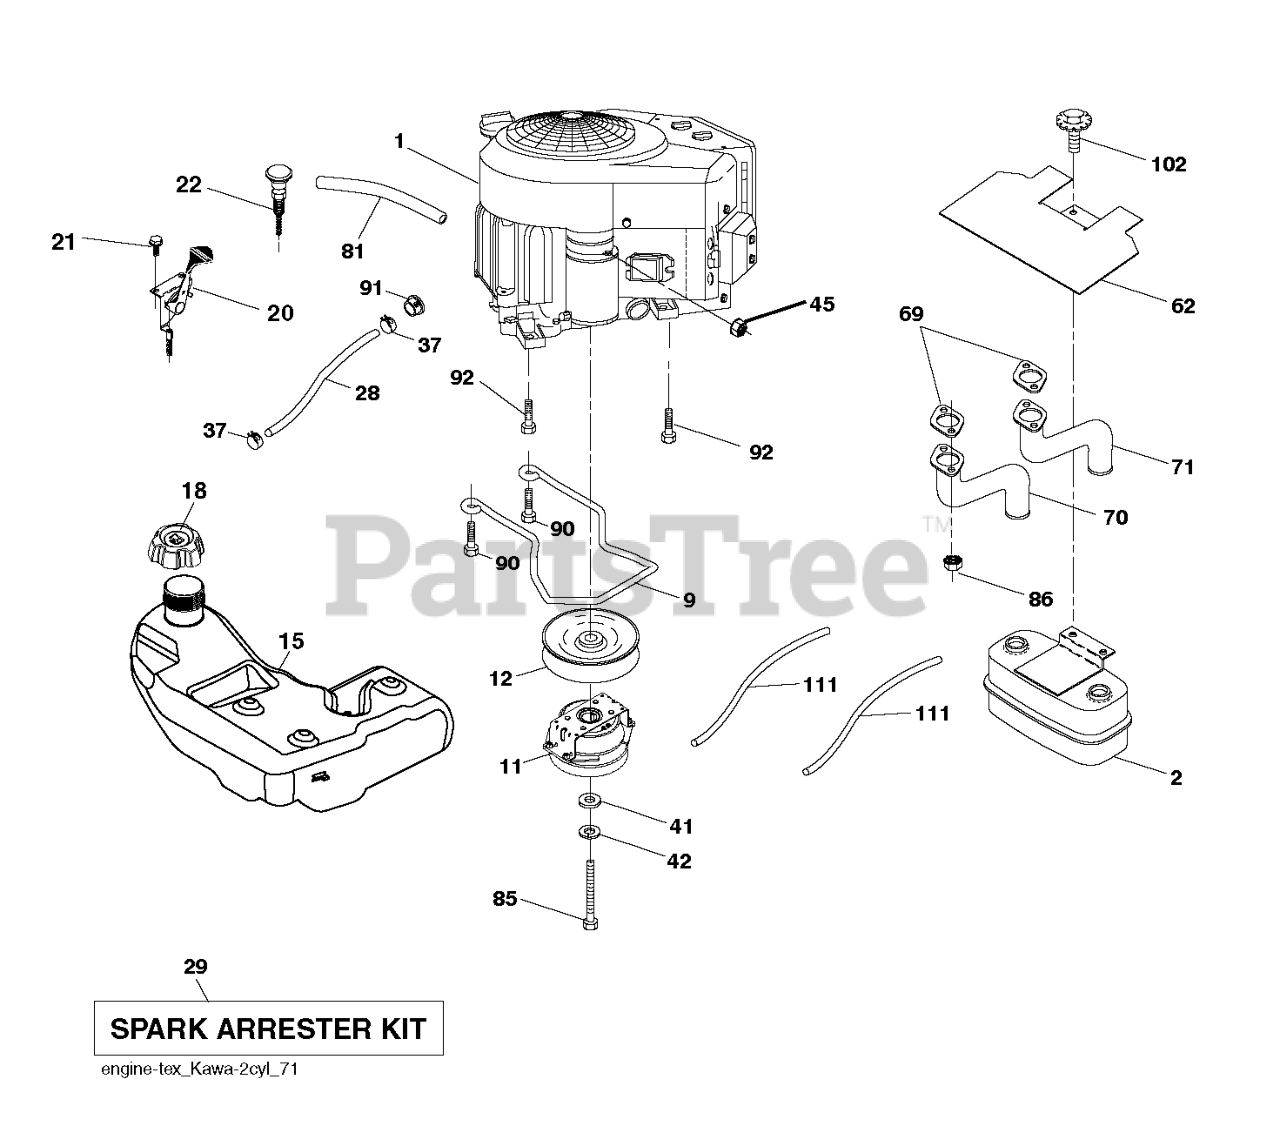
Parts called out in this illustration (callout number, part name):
2	MUFFLER.ASM.TWIN.MNTG.BRACKET
9	KEEPER.BELT.ENG.4.25"2.BLT.431
11	CLUTCH.OGURA.5.0PD.GT1.5A-EH07
12	PULLEY.ENGINE.TUFFTORQ
15	TANK.ASM.3GAL.EPA.17
18	CAP ASSY FUEL 3" GRAY
18	FUEL CAP
20	CONTROL.THROTTLE.COBRA.BLACK
21	SCREW.#10 X 0.750.BOS
22	CONTROL, CHOKE
28	LINE.FUEL.64"REAR.EMIS
29	KIT.SPARK ARRESTOR 794945 B&S
37	HOSE CLAMP
42	WASHER 7/16 LOCK
45	NUT
62	SHIELD.HEAT.MUFFLER
70	TUBE.EXHAUST.RH.FR961/FR730
71	TUBE.EXHAUST.LH.FR961/FR730
81	TUBE, DRAIN OIL ASM.
85	BOLT.HEX.7/16-20X3.75.GR5.RED
86	NUT.HEX.FLANGE.TOPLOCK
90	SCREW 3/8-16X1
91	BUSHING.1.375OD
92	SCREW 3/8-16X1
102	SCREW
111	RP PURGE LINE
